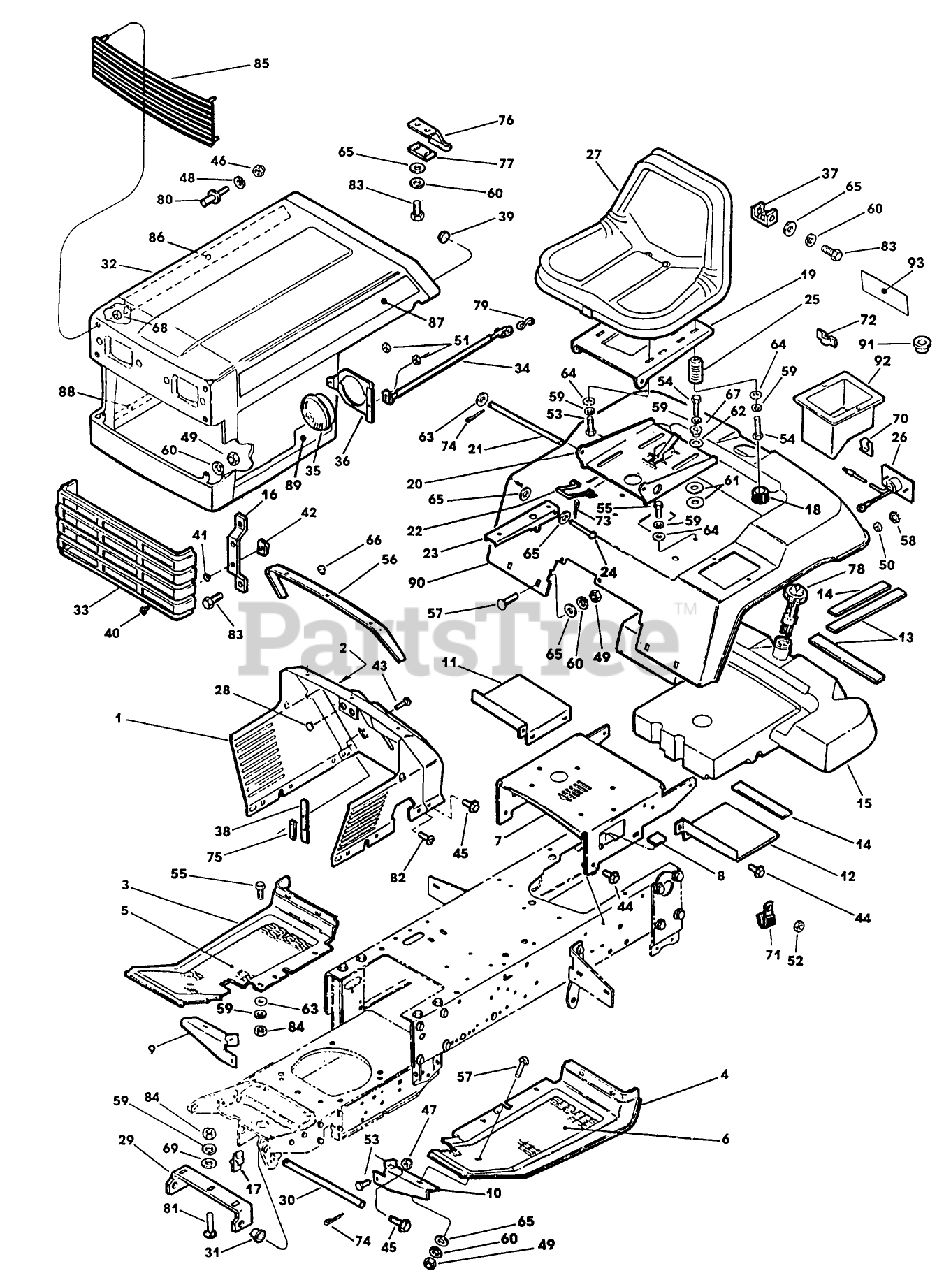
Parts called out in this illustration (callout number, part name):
14	PAD - FUEL TANK
15	TANK - FUEL
17	CLIP-RETAINER, WIRE
18	CAP-PROTECTOR
19	PIVOT AY - SEAT *B
20	SEAT SUPPORT AY
21	PIN
23	LATCH - SEAT PAN *B
24	PIN
26	TAILLIGHT
27	SEAT
30	ROD - HOOD PIVOT
31	BEARING-NYLINER
33	INSERT - GRILLE
40	FASTENER-1/4 TURN
47	NUT
49	NUT
53	SCREW - HEX
54	SCREW
61	WASHER-PLASTIC
63	WASHER
71	CLAMP - J EX
78	GUAGE ASSEMBLY-FUE
80	PIN - CATCH
83	SCREW-HH
84	NUT SS
87	DECAL - HOOD LH
